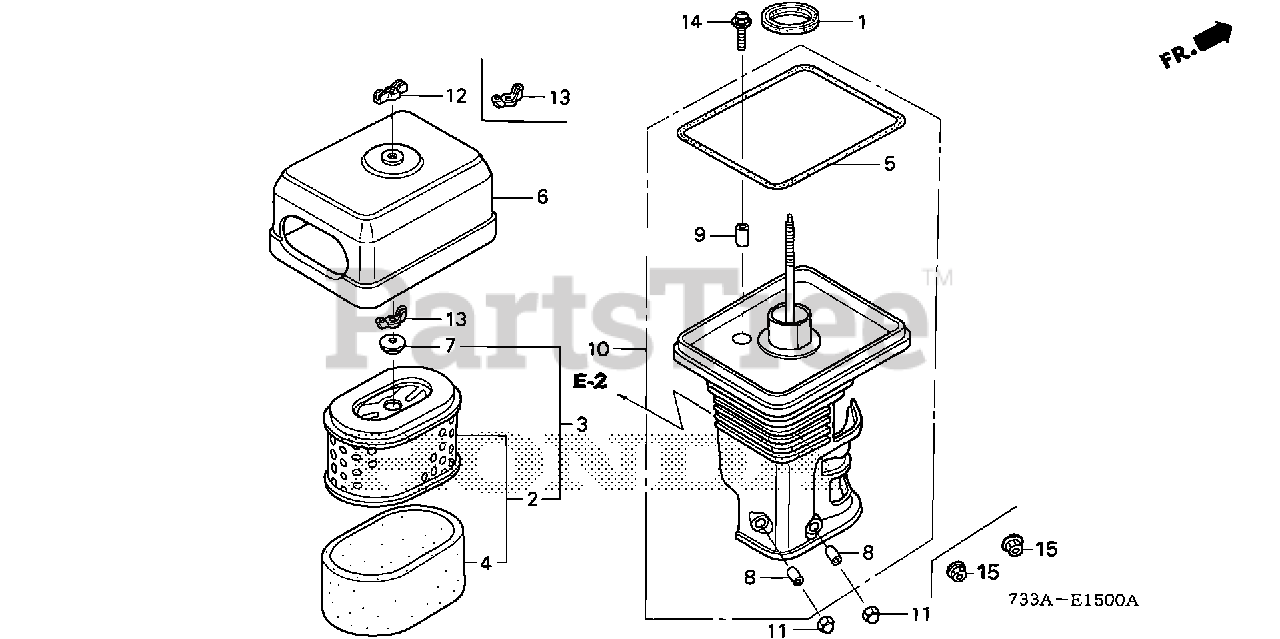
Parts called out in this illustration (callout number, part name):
1	GASKET, ELBOW
2	ELEMENT, AIR CLEANER (DUAL)
3	ELEMENT, AIR CLEANER (DUAL)
4	FILTER (OUTER)
5	GASKET, AIR CLEANER COVER
6	COVER, AIR CLEANER (DUAL)
7	GROMMET, AIR CLEANER
8	COLLAR, AIR CLEANER (NOT AVAILABLE)
8	COLLAR, AIR CLEANER
9	COLLAR B, AIR CLEANER
10	ELBOW, AIR CLEANER (NOT AVAILABLE)
10	ELBOW, AIR CLEANER
11	NUT, CAP (6MM)
12	NUT, AIR CLEANER COVER (DACRO COATING)
13	NUT, TOOL BOX SETTING
14	BOLT, FLANGE (6X20)
